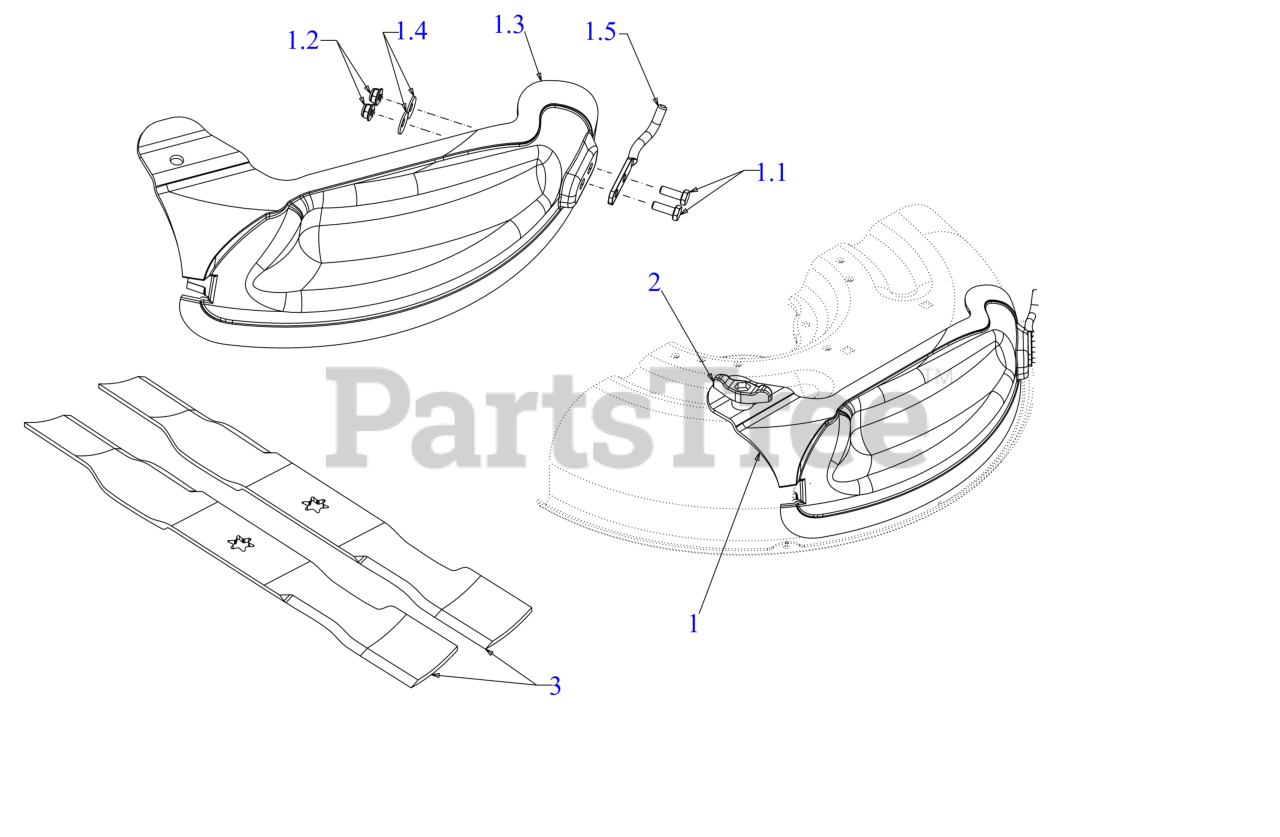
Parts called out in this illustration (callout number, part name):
1	MULCH PLUG ASSEMBLY
1.1	SCREW 1/4-20X.75 GR5
1.2	FLANGE LOCK NUT
1.3	MULCH PLUG
1.4	SPRING WASHER BELL
1.5	MULCH PLUG MOUTING ROD
2	WING KNOB 5/16-18
3	23.25" BLADE (MULCH)
3	Cub Cadet 46" MULCH BLADE SET
3	Genuine Factory Parts 46" MULCH BLADE SET
